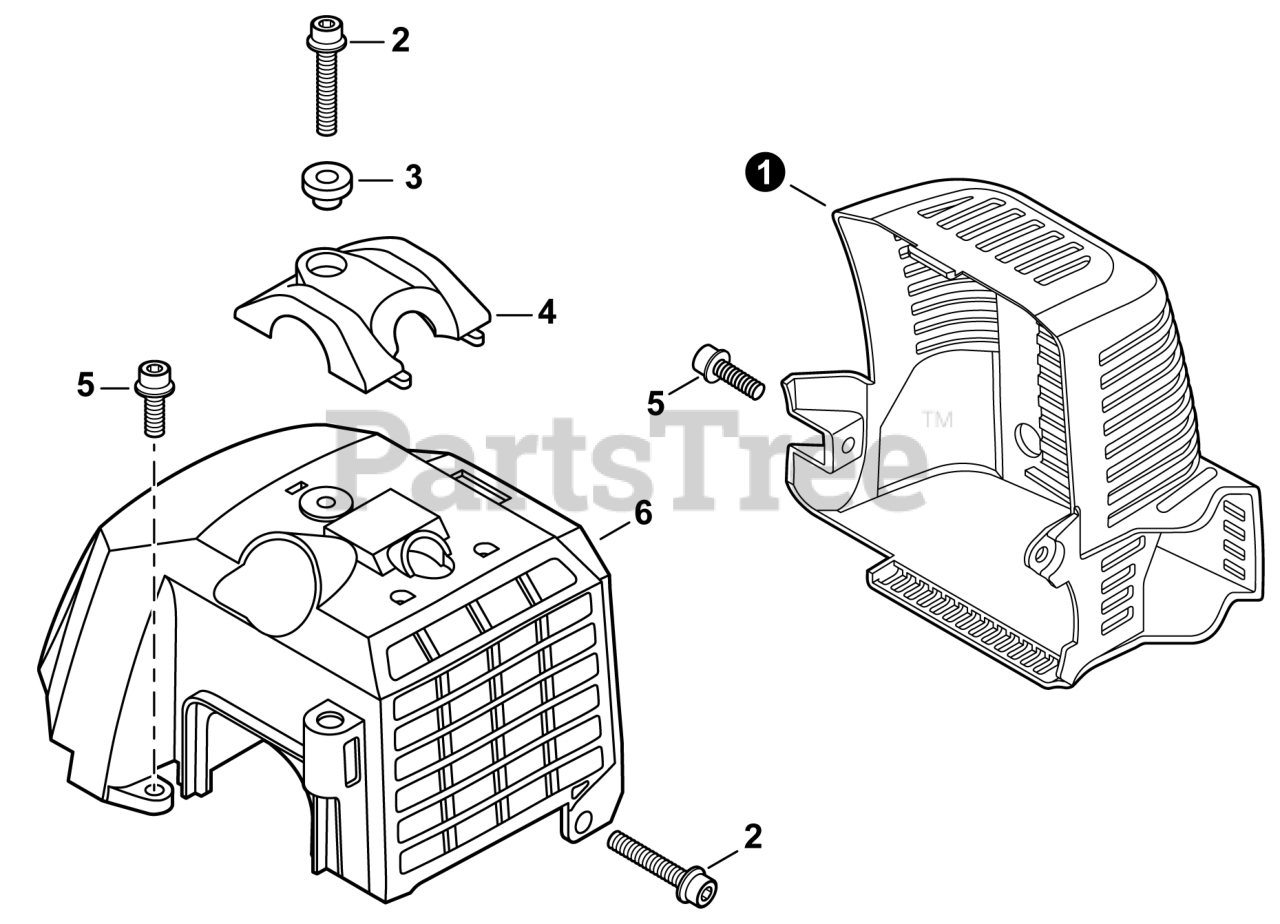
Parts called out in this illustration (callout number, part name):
1	COVER, MUFFLER
2	BOLT 5x20
3	COLLAR 5
4	GUARD, TOP
5	BOLT 5x12
6	COVER, ENGINE
